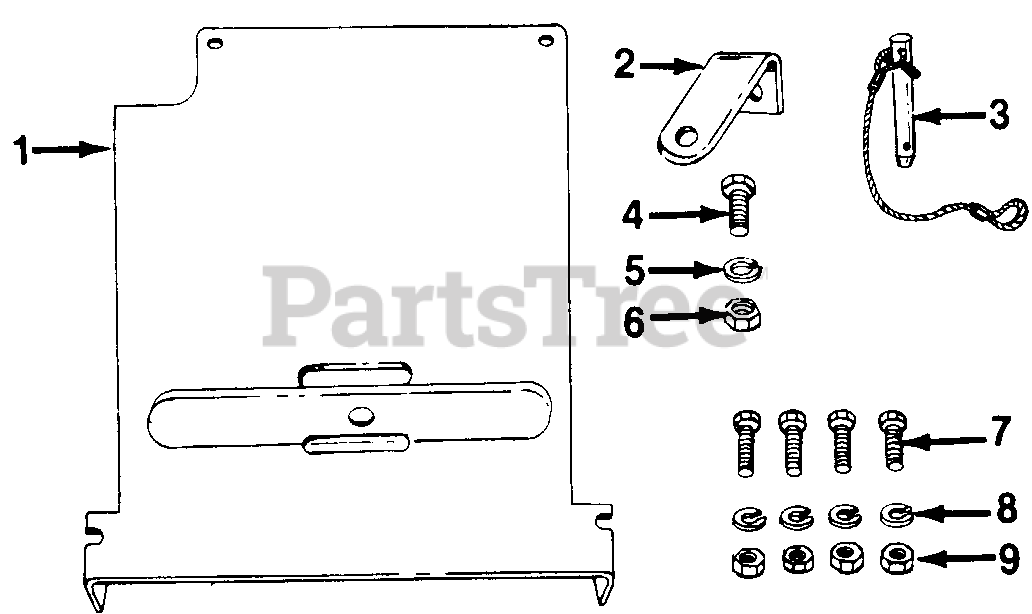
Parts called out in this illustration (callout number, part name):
1	Hitch Plate
2	Hitch Bracket
3	Hitch Pin
4	Hex Scr. 3/8-16 x 1" Lg.
5	L-Wash. 3/8" Scr.*
6	Hex Nut 3/8-16 Thd.
7	Hex Scr. 5/16-18 x .75" Lg.
8	L-Wash. 5/16" Scr.
9	Hex Nut 5/16-18 Thd.
